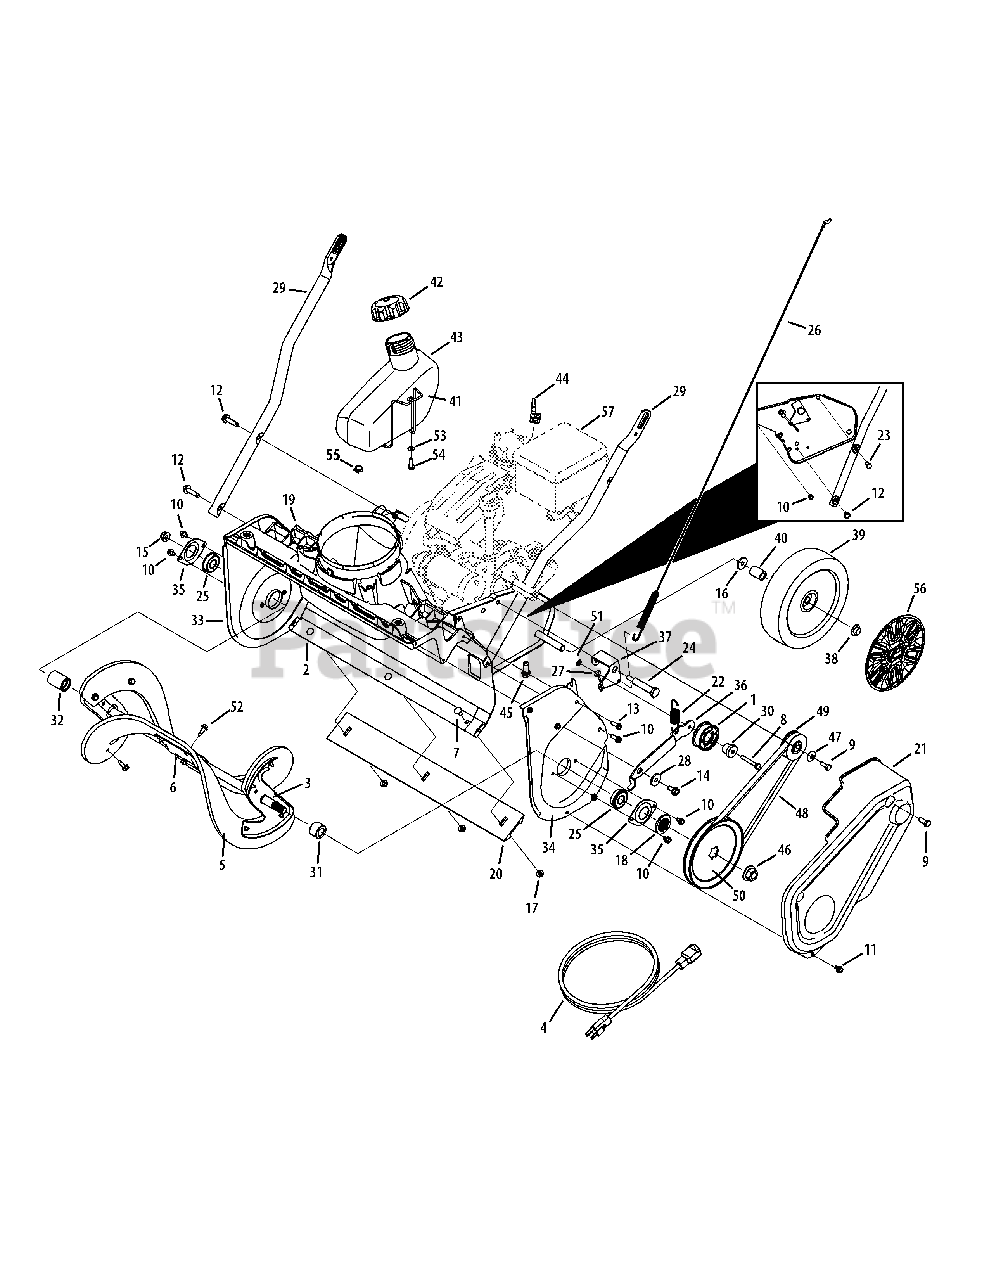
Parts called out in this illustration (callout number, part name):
1	Idler Pulley Assembly
2	Frame
3	Auger Assembly Mount
4	3-Prong Extension Cord
5	Auger Rubber Replacement Kit
6	Center Auger Bracket
6	Hex Washer Bolt 1/4-20 x.750
7	Carriage Screw, 1/4-20 x .62
8	Hex Screw, 1/4-20 x 1.50
9	Hex Lock Screw, 5/16-24 x .875
10	Hex Washer Screw, 1/4-20 x .750
11	Hex Washer Screw, 1/4-20 x .500
12	Hex Washer Screw, 5/16-18 x 1.250
13	Hex Washer Screw, 1/4-15 x .750
14	Hex Washer Screw, 5/16-18 x .75
15	Flange Lock Nut, 3/8-16
16	Flat Washer, .535 x .930 x .090
17	Flange Lock Nut, 1/4-20
18	Pulley Hub
19	Chute Adapter
20	Shave Plate
22	Extension Spring, .70 x 3.035
23	Hex Screw, 5/16-24 x 1.25
24	Shoulder Bolt, 5/16-24 x .496 x 2.18
25	Ball Bearing, .500 x 40mm x 12mm
26	Clutch Cable
27	Drive Cable Wire Support
28	Shoulder Spacer
30	Shoulder Spacer, .260 x .785 x .538
31	LH Auger Spacer
32	RH Auger Spacer
33	RH Auger Plate
34	LH Auger Plate
36	Idler Bracket
37	Cable Idler Bracket
38	Push Cap, 1/2
40	Sleeve Spacer, .525 x .775 x .835
41	Gas Tank Wire Support
42	Fuel Cap
43	Fuel Tank
44	Choke Extension Lever
45	Hex Washer Screw, 3/8-16 x 1.000
46	Flange Nut, 7/16-20
47	Thrust Washer, .330 x 1.25 x .120
48	Belt, .500 x 35.06
49	Pulley Half, .625 x 2.25
50	Pulley, 1/2 x 6.00
52	Hex Washer Screw, 1/4-20 x .750
53	Washer, .265 x 1.00 x .030
54	Screw, 1/4-10 x .625
55	Hose Clamp
57	Replacement Engine
